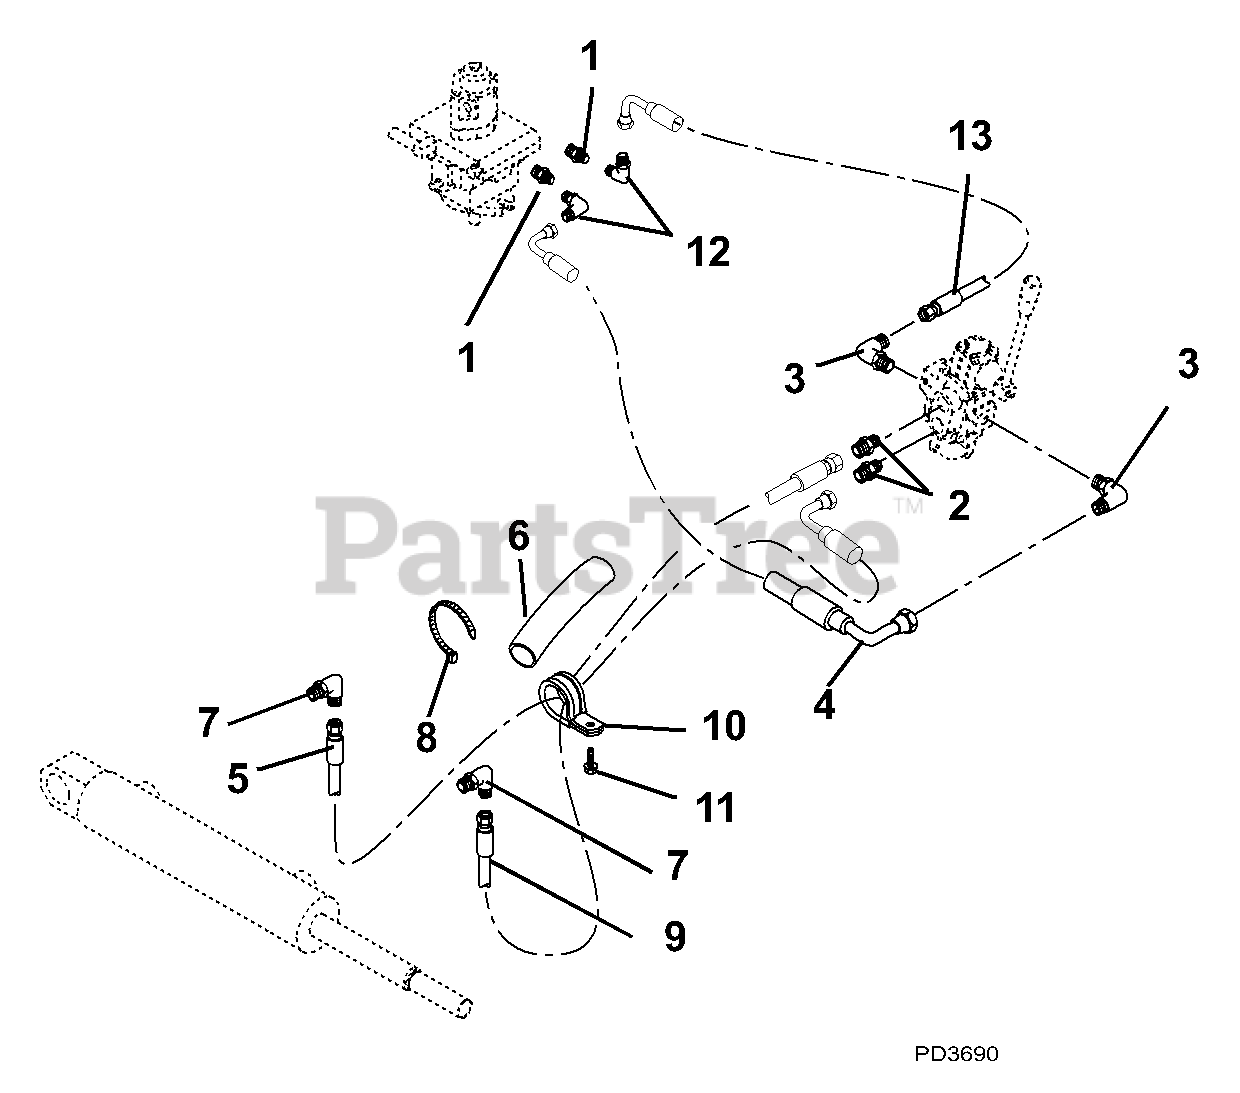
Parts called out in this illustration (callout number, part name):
1	Fitting, Hydraulic
2	Fitting, Hydraulic
3	Fitting, Hydraulic Elbow
4	Hose, Hydraulic
5	Hose, Hydraulic
6	Sleeve, Protective
7	Fitting, Hydraulic Elbow
8	Cable Tie
9	Hose, Hydraulic
10	Clamp, Steel 1.0
11	Screw-Tapping .25-20 X .50 Hex Washer Head Thread
12	Fitting, Hydraulic Elbow
13	Hose, Hydraulic
